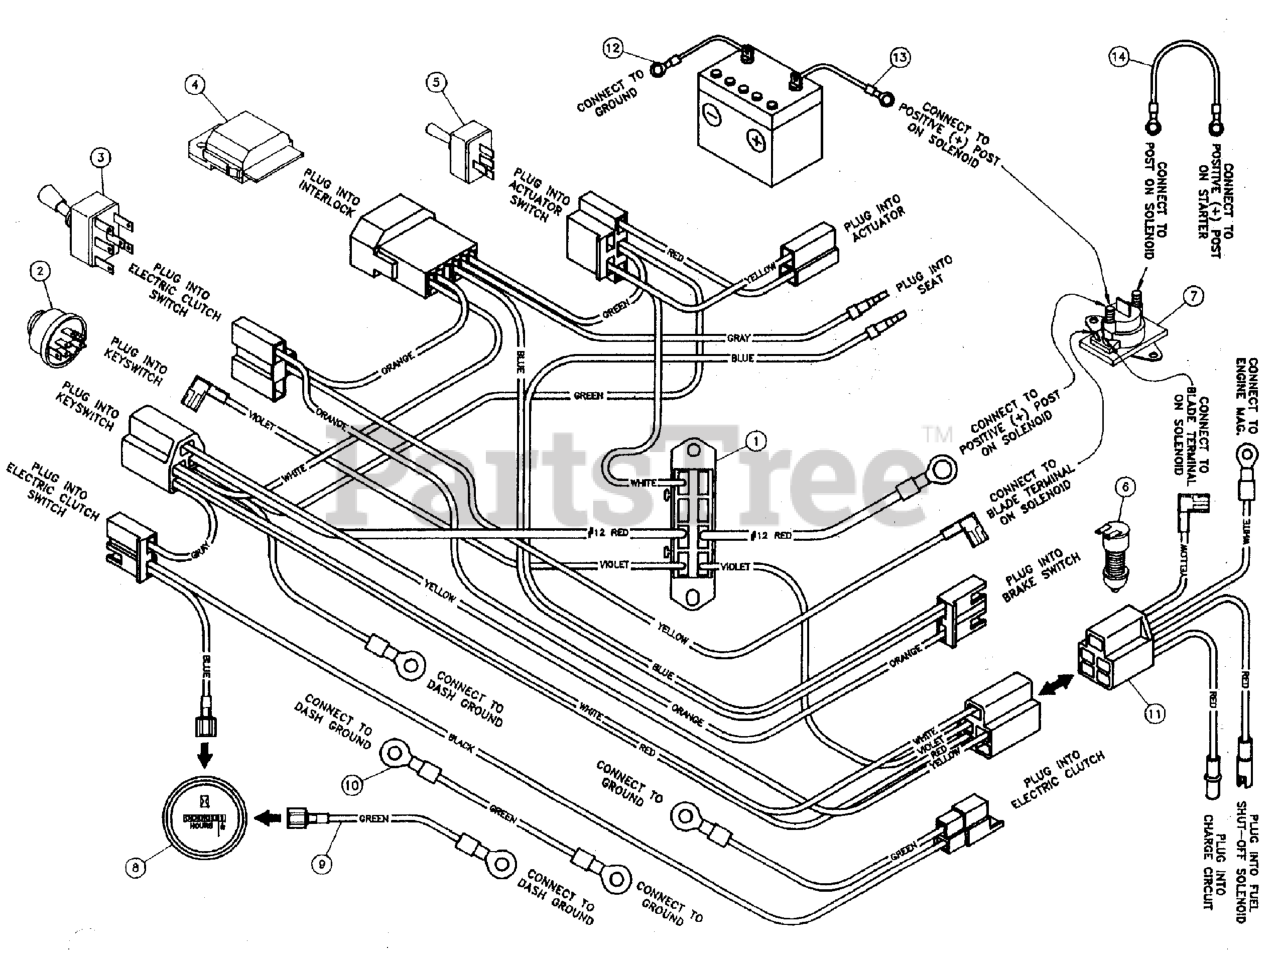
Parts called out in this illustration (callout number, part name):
1	RIDER WIRE HARNESS
2	SWITCH, IGNITION, 6 POST
3	SWITCH, Electric Clutch
4	1601 Interlock
5	SWITCH, Actuator
6	SWITCH, Plunger, NO
7	SOLENOID, Starter
8	HOUR METER
9	HOUR METER GROUND WIRE
10	DASH GROUND WIRE
11	Briggs Adapter Harness
12	BATTERY CABLE, NEG, 22, 1/4-5/16
13	POSITIVE (+) BATTERY CABLE, 30"
14	STARTER CABLE
